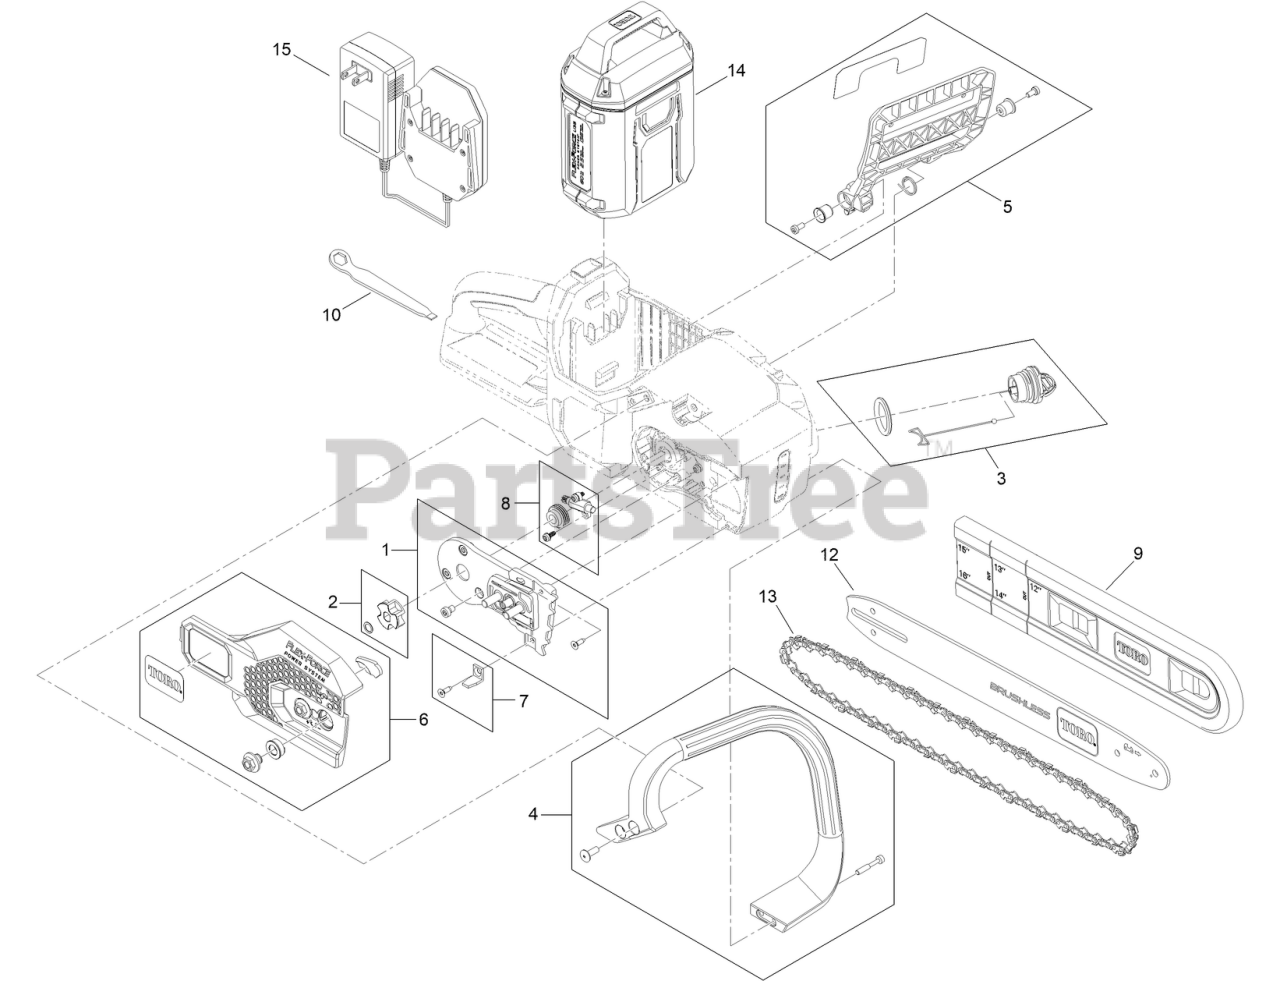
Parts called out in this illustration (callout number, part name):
1	ADJUSTER BAR BRACKET ASM
2	DRIVE GEAR ASM
3	OIL CAP ASM
4	HANDLE ASM
5	CHAIN BRAKE ASM
6	BAR COVER ASM
7	BAR COVER SUPPORT BRACKET ASM
8	OIL PUMP ASM
9	BAR-SLEEVE, CHAINSAW
10	TOOL-ADJUSTMENT, BAR
12	BAR-REPLACEMENT
13	CHAIN
14	BATTERY-60V 2.0AH
15	CHARGER-BATTERY, 60V 1 AMP
